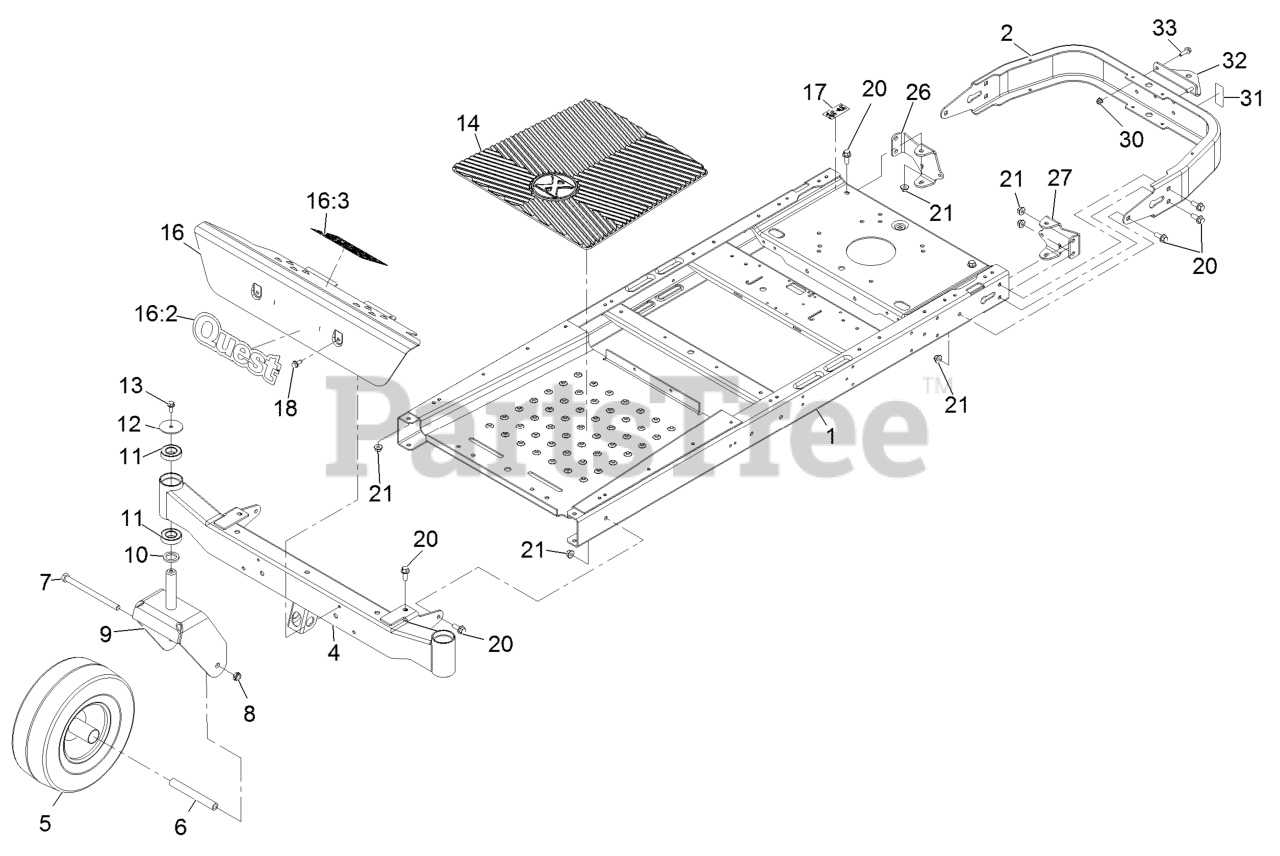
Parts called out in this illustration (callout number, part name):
2	BUMPER-REAR
4	AXLE-FRONT
5	CASTER WHEEL ASM
6	BUSHING-SPANNER
7	SCREW-HH
8	NUT-HEX
9	FORK-CASTER
10	WASHER-THRUST
11	BEARING-BALL
13	SCREW-HHF
14	MAT-FLOOR
16	FOOTREST ASM
17	DECAL-BYPASS
18	Screw-HWH 5/16-18 X 3/4 Tf
20	SCREW-HHF 3/8-16 X 1
21	NUT-HF, NI
26	MOUNT-HYDRO, REAR (RH)
27	MOUNT-HYDRO, REAR (LH)
30	NUT-HF, NI
32	BRACKET-HITCH
33	SCREW-HHF
